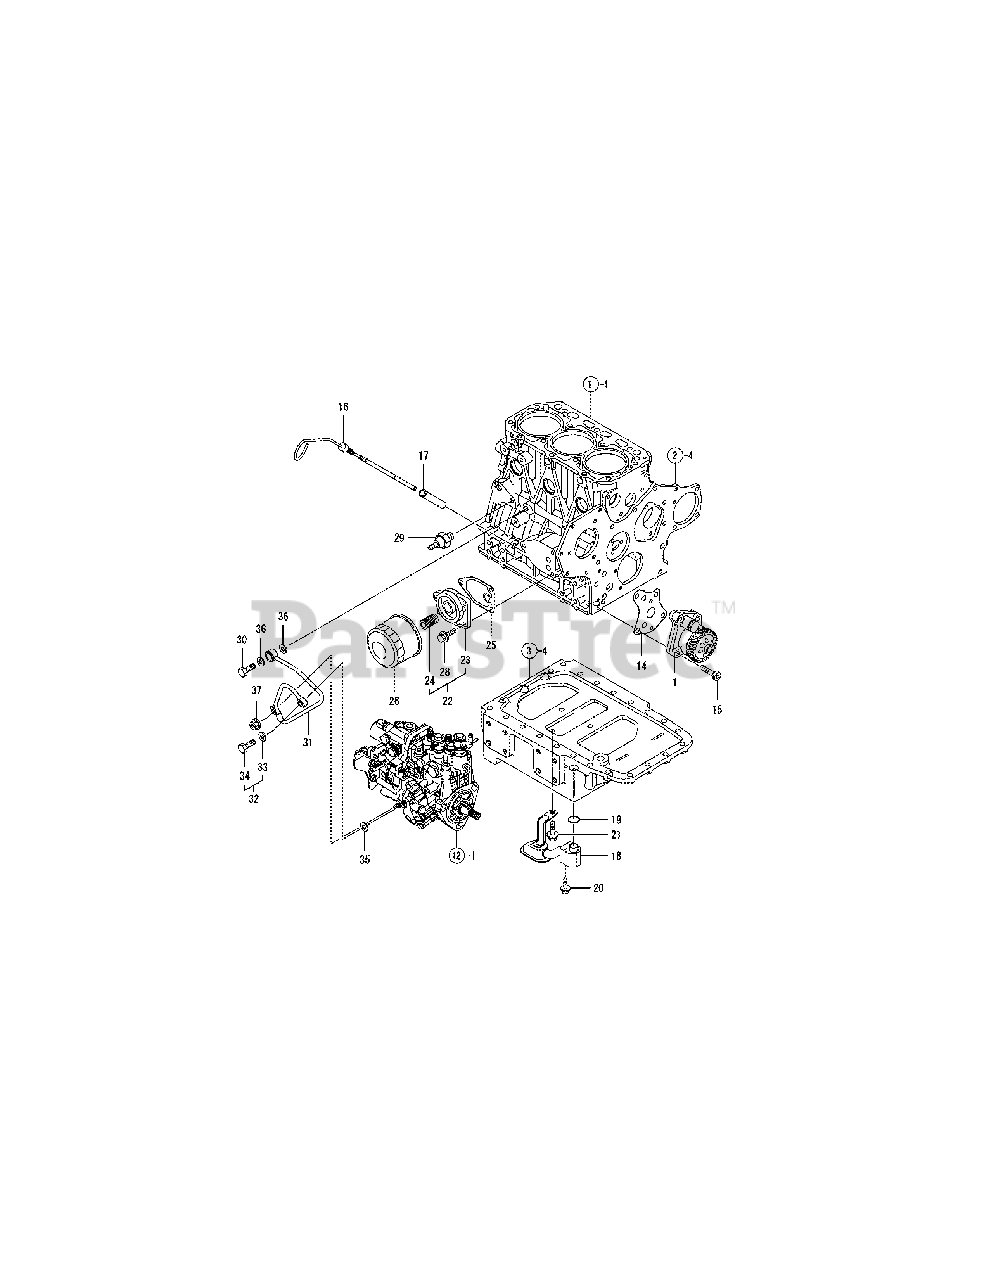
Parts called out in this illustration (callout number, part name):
1	PUMP ASSY, LUB. OIL
14	GASKET, L.O. PUMP
16	DIPSTICK, LUB.OIL
17	GUIDE, DIPSTICK
18	PIPE ASSY, INLET
19	O-RING 1A P-16.0
20	BOLT M 6X 40 PLATED
21	BOLT M 8X 12 PLATED
22	BRACKET ASSY, FILTER
23	BRACKET, FILTER
25	GASKET, (NON-ASB.)
28	BOLT M 8X 20 PLATED
29	SWITCH,(0.5KG)L.O.
30	BOLT 10, PIPE JOINT
31	PIPE ASSY, LUB. OIL
32	BOLT ASSY, JOINT
33	SEAL WASHER 8S
35	SEAL WASHER 8S
36	SEAL WASHER 10S
